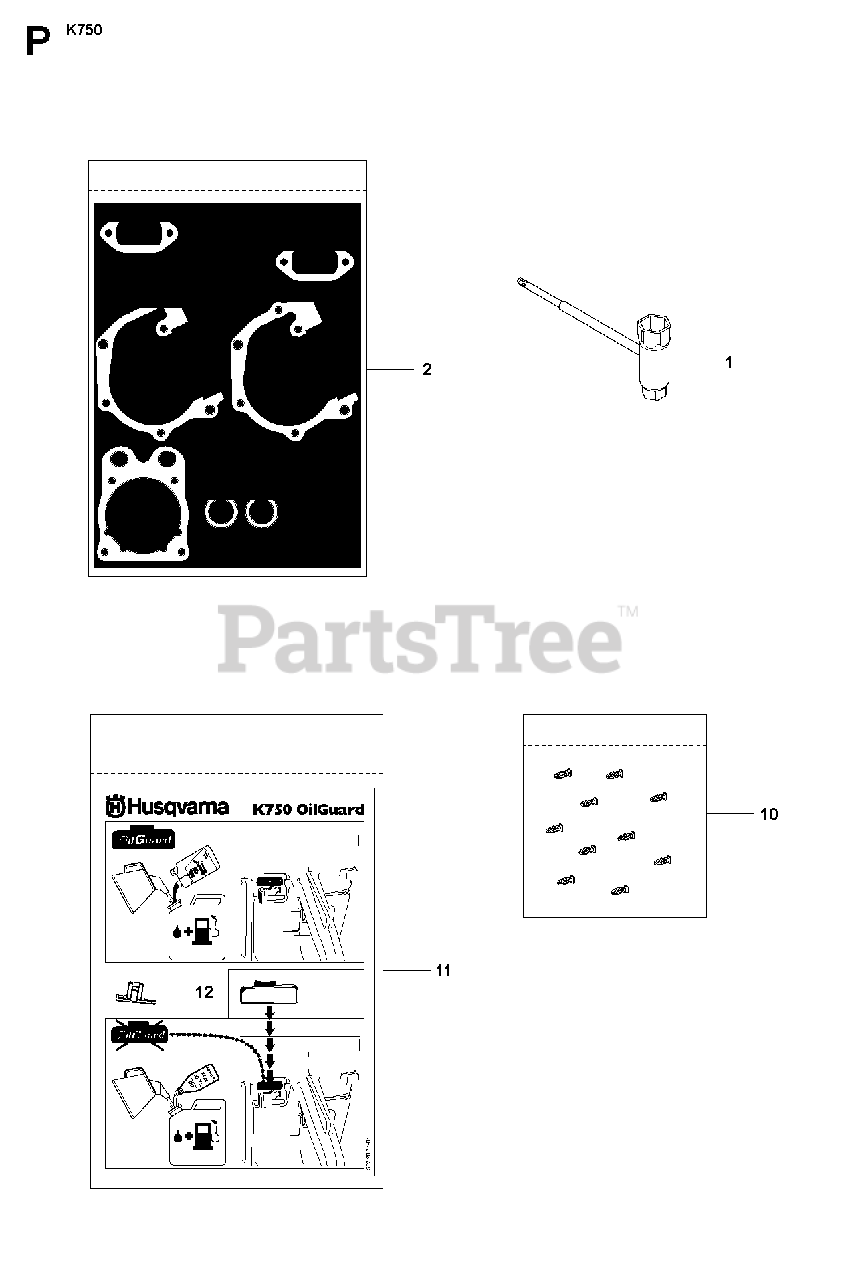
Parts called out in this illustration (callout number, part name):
2	GASKET KITIncl. 3 - 8
4	GASKET
8	CYLINDER BASE GASKET
9	SEALING RING
10	KITIncl. 10 Springs
11	KIT
